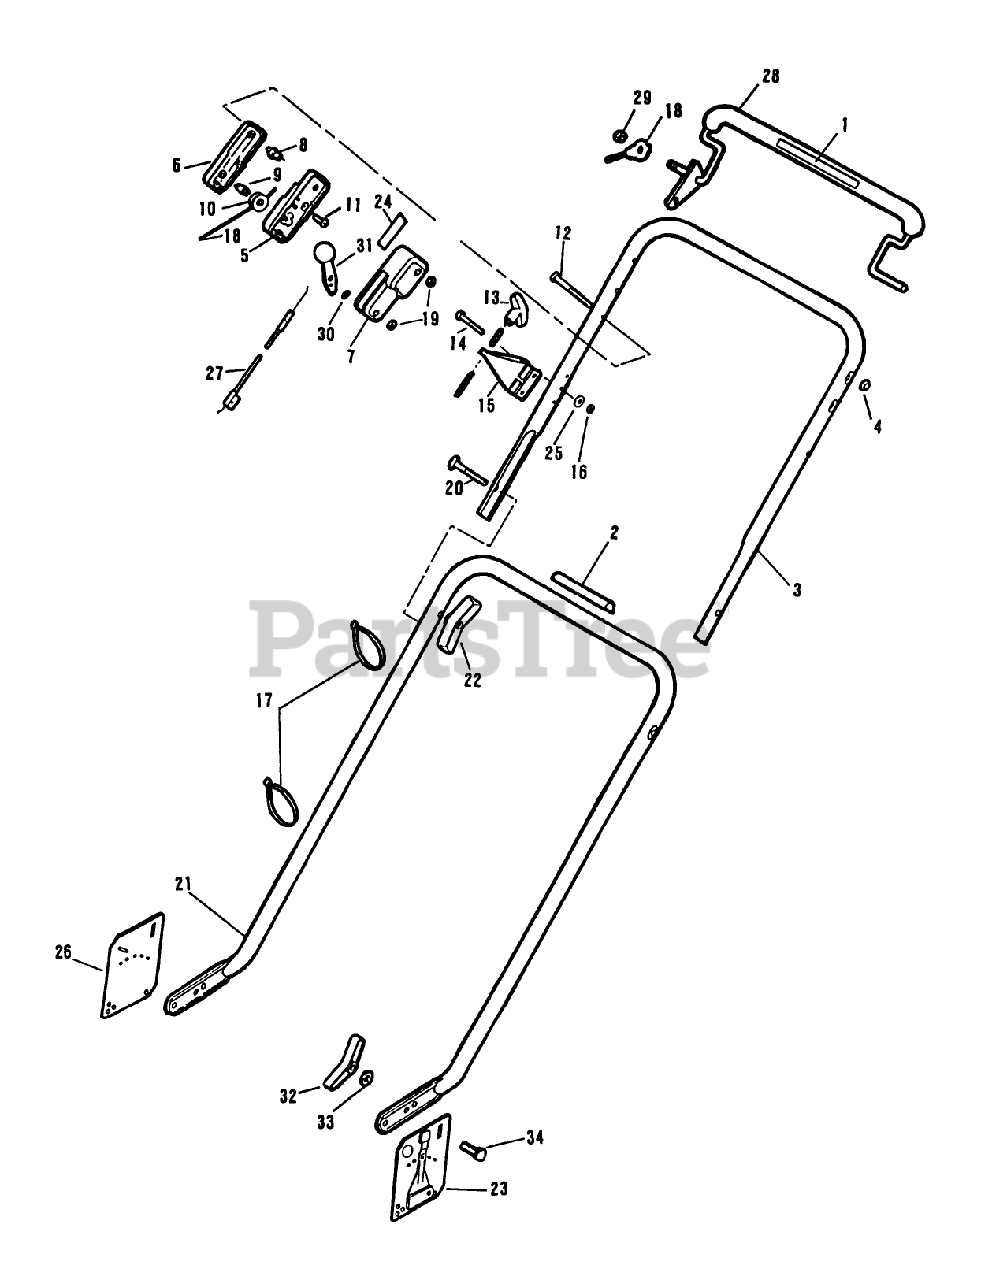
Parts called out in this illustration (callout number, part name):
6	OUTER CONTROL CASE
8	COLUMN
9	PIN SKF
10	PULLEY PL
11	SCREW
12	SCREW
13	HANDLE START UM&D
16	LOCKNUT E
18	CONTROL CABLE
19	NUT C/LOCK E
20	BOLT QUALITY
22	NUT-WING
25	WASHER
27	CABLE TH'TTLE WES
28	CONTROL LEVER ARG
29	NUT ACORN
30	WASHER-SPRING
31	LEVER&KNOB AY WES
32	NUT WING
